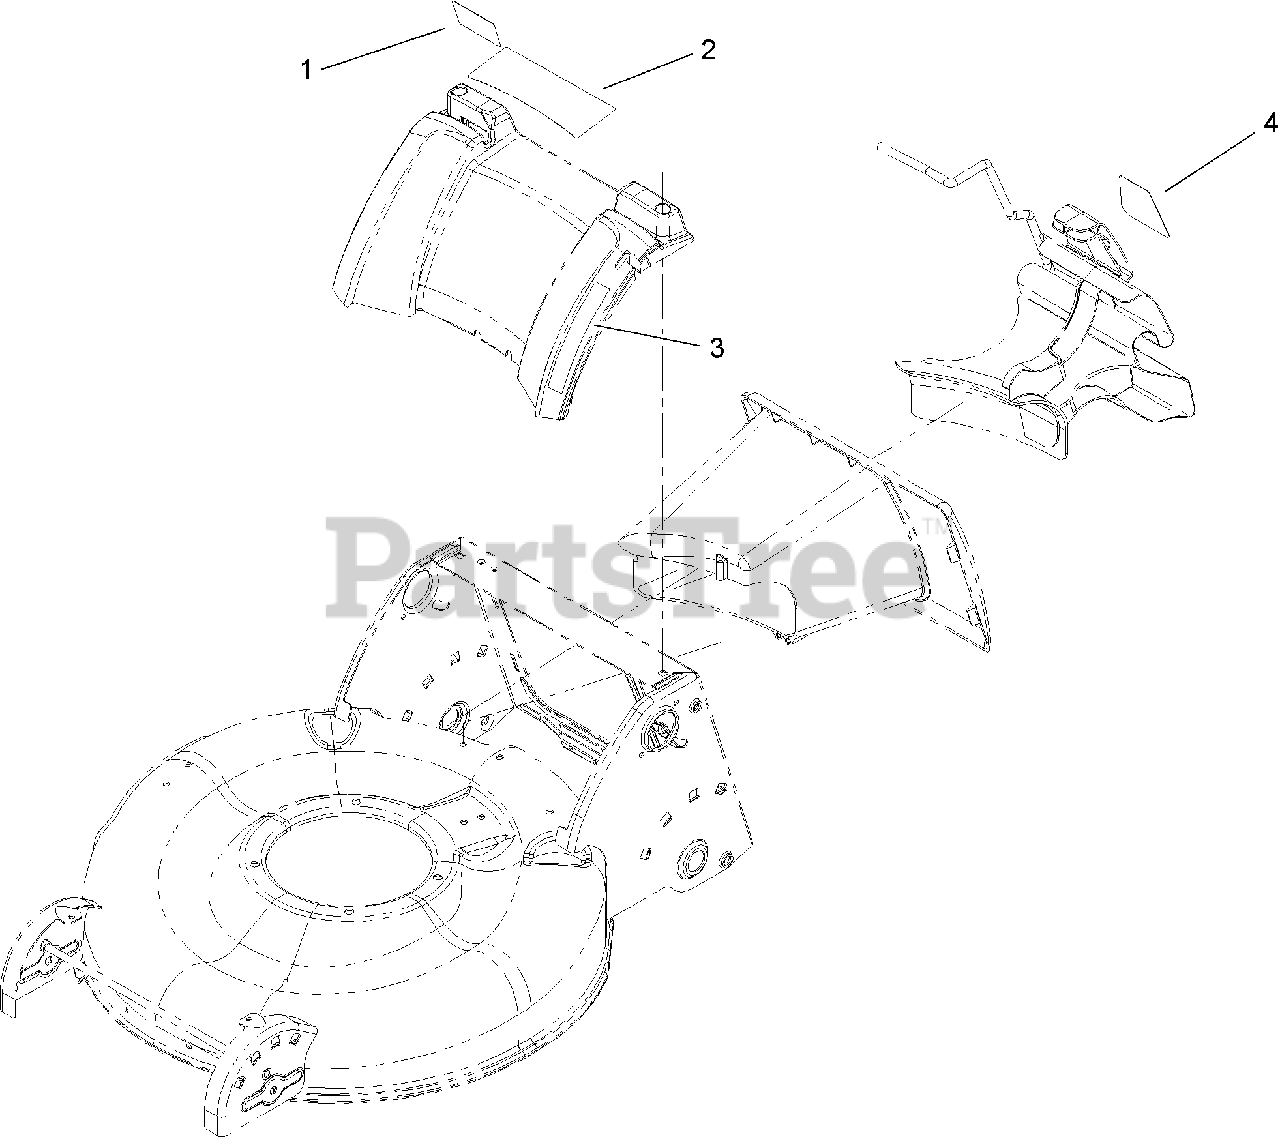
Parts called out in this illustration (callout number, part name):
1	DECAL-BAG ATTACHMENT, CE
2	DECAL-WARNING
3	DECAL-POS,QR,CE
4	DECAL-MULCH PLUG, CE
